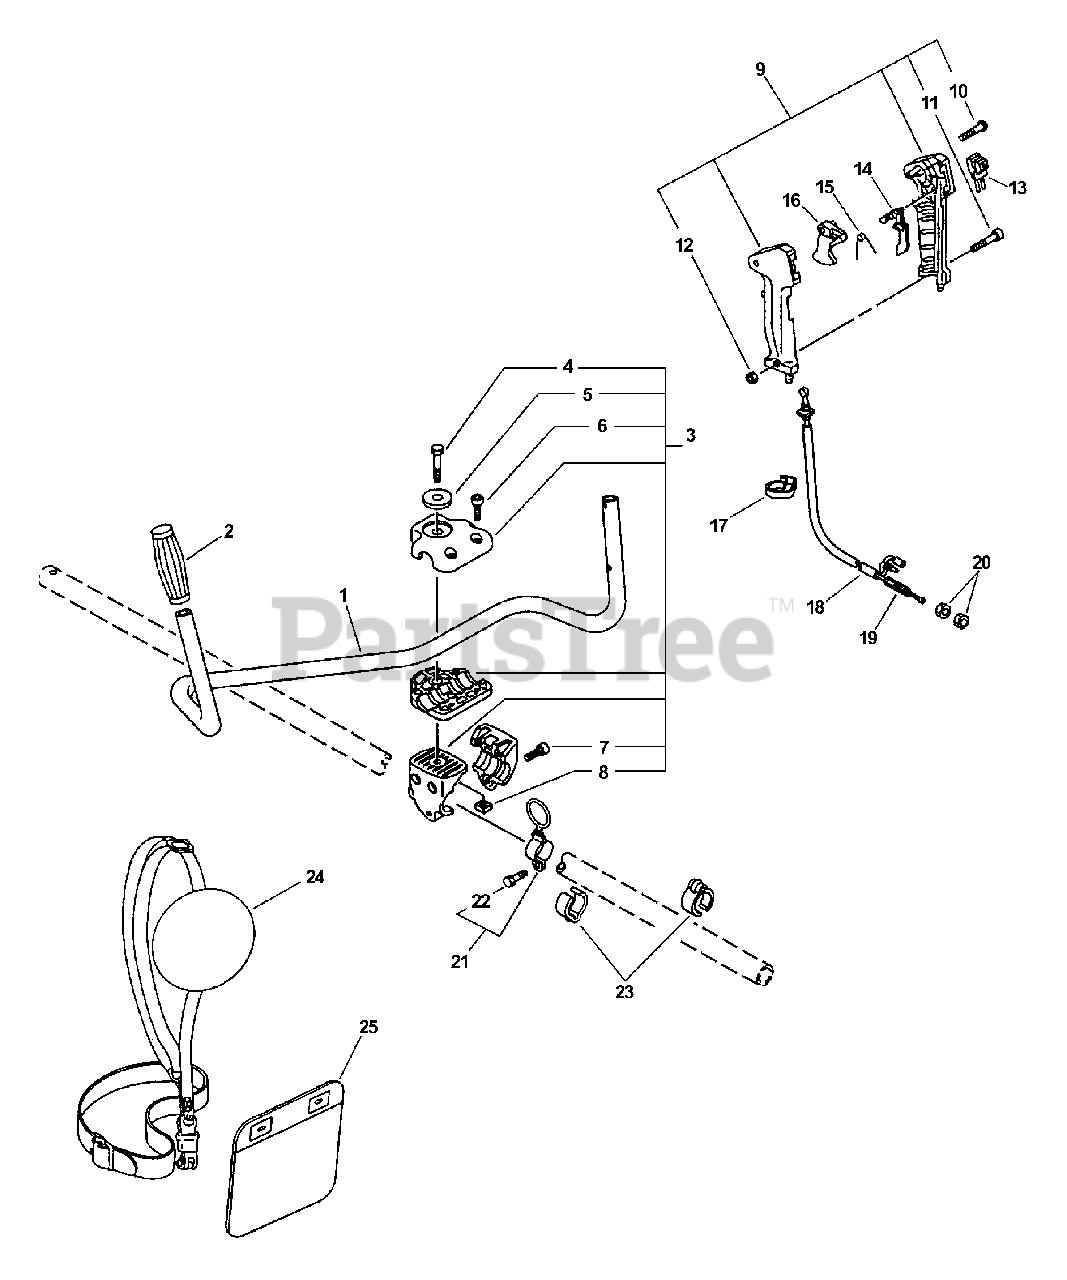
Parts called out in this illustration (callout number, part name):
1	HANDLE - FRONT
2	GRIP, HANDLE - LEFT
3	HANDLE BRACKET KIT
4	BOLT - 8X55
5	WASHER - 8
6	SCREW - 5X20
7	SCREW - 5X30
9	THROTTLE CONTROL ASSY
10	SCREW - 3X25
11	SCREW - 5X30
13	IGNITION SWITCH ASSY
14	LOCKOUT, THROTTLE
15	SPRING, LOCKOUT LEVER
16	TRIGGER, THROTTLE
18	TUBE, PROTECTIVE - CORRUGATED
19	CABLE, THROTTLE
21	HANGER KIT
22	BOLT - 5X12
24	SHOULDER STRAP ASSY
25	CUSHION
